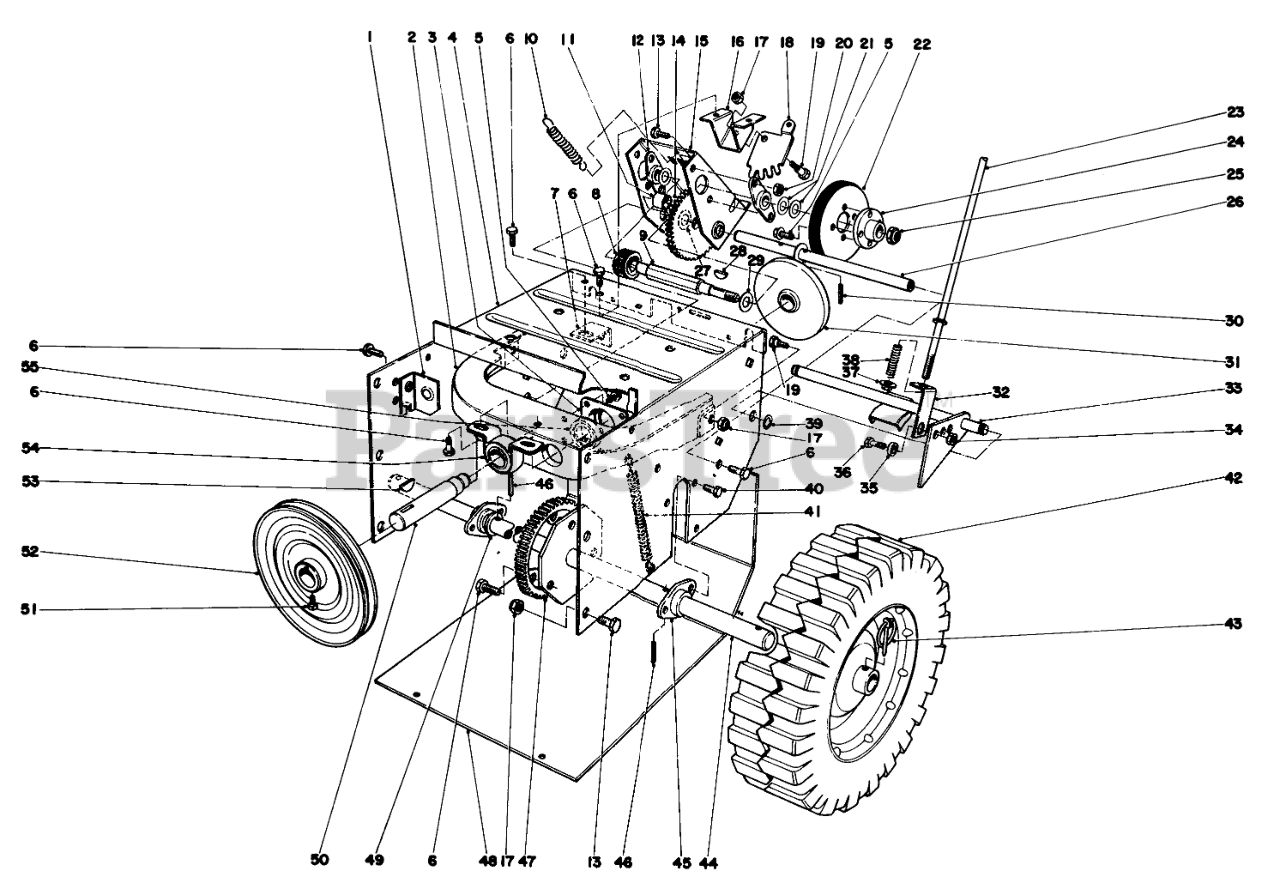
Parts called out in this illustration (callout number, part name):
1	AUGER CLUTCH MTG FRT
2	"OBS" FRICTION PLT FRAME
3	CUP-BEARING
4	Frame-Traction
5	SCREW
6	SCREW-HWHTF
7	BRACKET-MOUNT, REAR
8	PINION
9	SHAFT-WHEEL, FRICTION
10	SPRING-TRACTION
11	5/8ID X 1LG BUSHING
12	BEARING-WHEEL, FRICTION
13	SCREW-HH
14	Intermediate Gear (Incl. Ref. #11)
15	Bracket Sliding
16	MOUNT-LEVER
17	NUT-LOCK, NI
18	GEAR-QUADRANT
19	BOLT-SHOULDER
20	NUT-LOCK, CONE
21	Washer
22	WHEEL-FRICTION
23	Lower Traction Rod
24	Hub-Friction Wheel Mounting
25	NUT-LOCK, NI
26	Shaft-Pivot
27	WASHER-SPECIAL
28	HI PRO KEY
29	WASHER-FLAT
30	PIN-SPRING
31	PLATE-FRICTION
32	BRACKET-TRACTION
33	Traction Engagement Arm
34	NUT-LOCK, CONE
35	Spacer-Traction Bracket
36	SCREW-HH
37	NUT-LOCK, HHF
38	SPRING
39	RING-RETAINING
40	Screw
41	SPRING-PLATE, FRICTION
42	Wheel
43	PIN-LYNCH
44	AXLE SHAFT WA
45	BEARING-AXLE
46	PIN-SPRING
47	GEAR-AXLE
48	Bottom Cover
49	WASHER-THRUST
50	Shaft Friction Plate
51	SCREW-SET, SQH
52	Pulley
53	KEY-WOODRUFF
54	BUSHING ASM
55	Bearing
